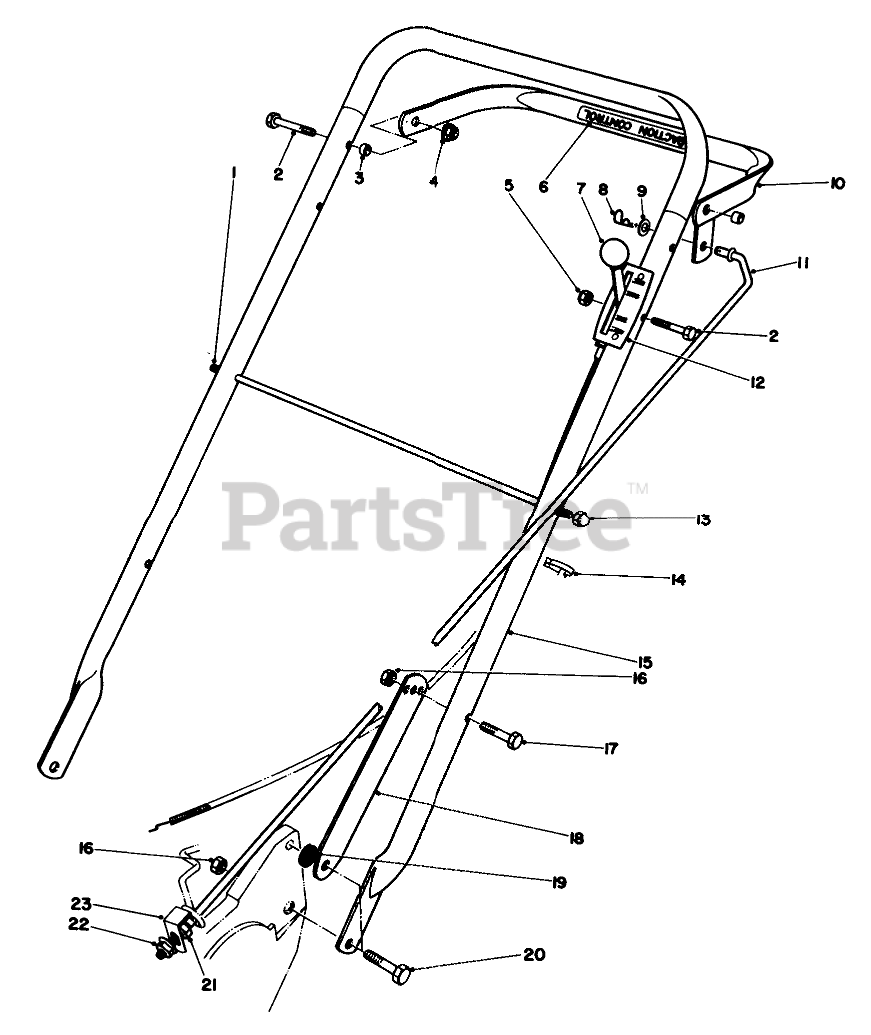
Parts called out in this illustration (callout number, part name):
1	ROD-SUPPORT, BAG
2	SCREW-HH
3	STANDOFF LIFT BAIL
4	NUT-LOCK, HHF
5	NUT-LOCK, NI
6	TRACTION DECAL
7	KNOB-CONTROL
8	PIN-COTTER
9	WASHER-PLAIN
10	CONTROL BAIL ASM
11	CONTROL ROD
12	Control-Throttle
13	NUT-CAP
15	Handle
16	NUT-LOCK, CONE
17	SCREW-HH
18	Latch-Handle
19	SPACER
20	SCREW-SHOULDER
21	LOCKNUT
22	NUT-FLANGE
23	ROD STOP BRACKET
